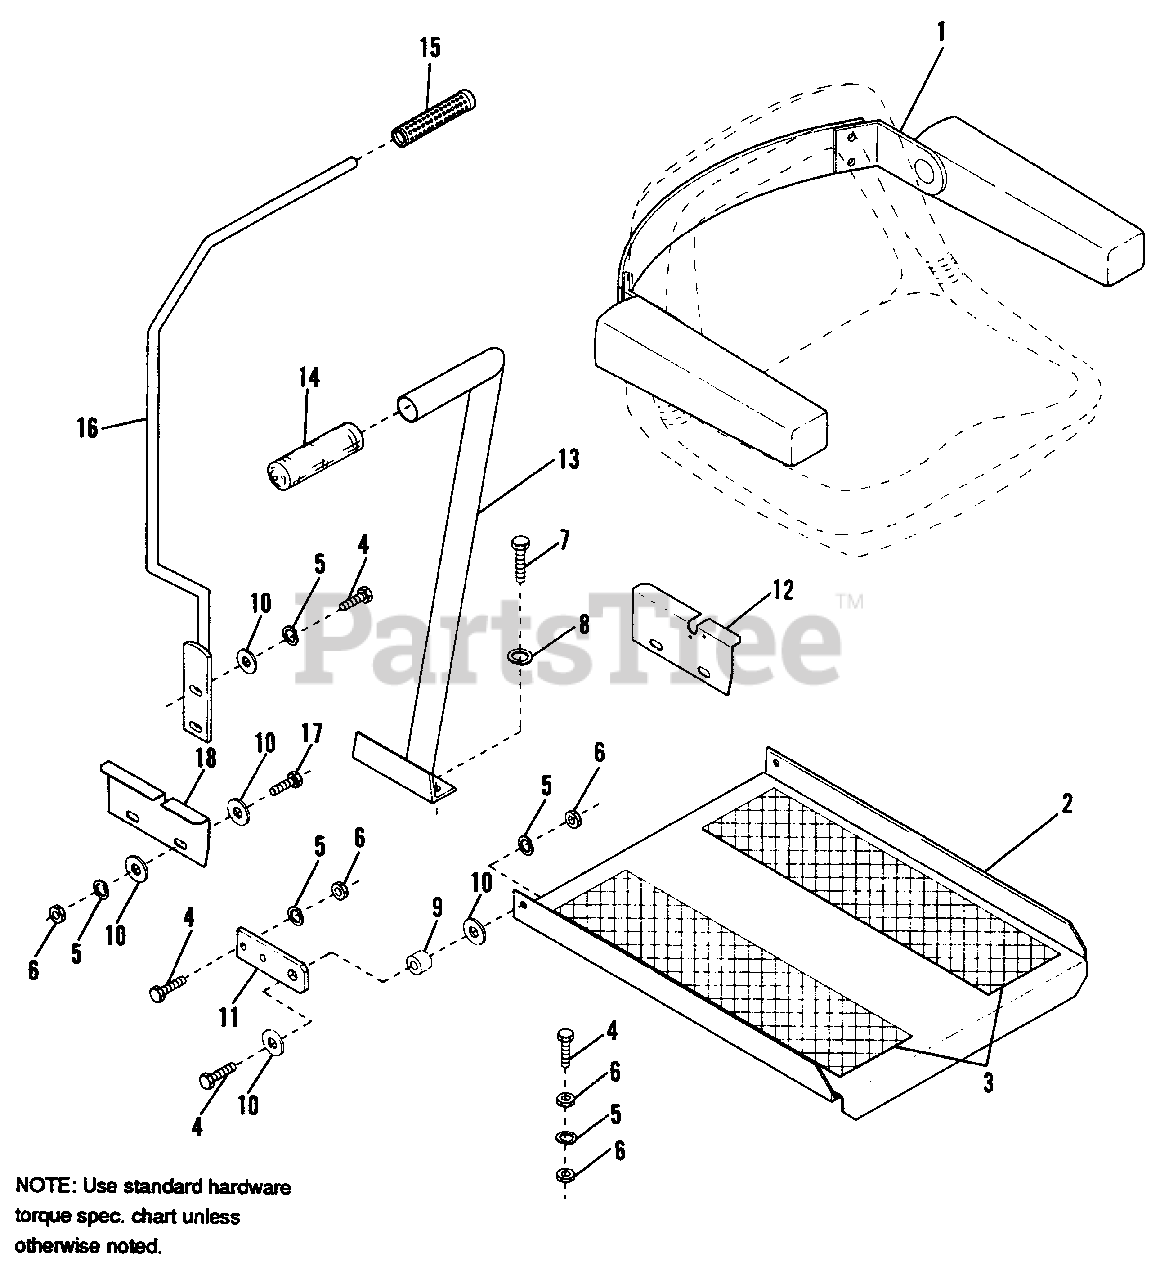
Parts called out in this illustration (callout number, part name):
1	ARM KIT, Seat
2	FOOTREST ASSY.
3	PAD, Non-Skid
4	CAPSCREW, Hex 5/16-18 x 1
5	LOCKWASHER, Spring 5/16
6	NUT, Hex 5/16-18
7	CAPSCREW, Hex 3/8-16 x 1
8	LOCKWASHER, Spring 3/8
10	WASHER, Plain
11	BRACKET, Footrest
12	PLATE, Neutral, Left Hand
13	HANDRAIL ASSY.
15	GRIP, Handle
16	HANDLE ASSY.
17	CAPSCREW, Hex 5/16-18 x 3/4
18	PLATE, Neutral, Right Hand
